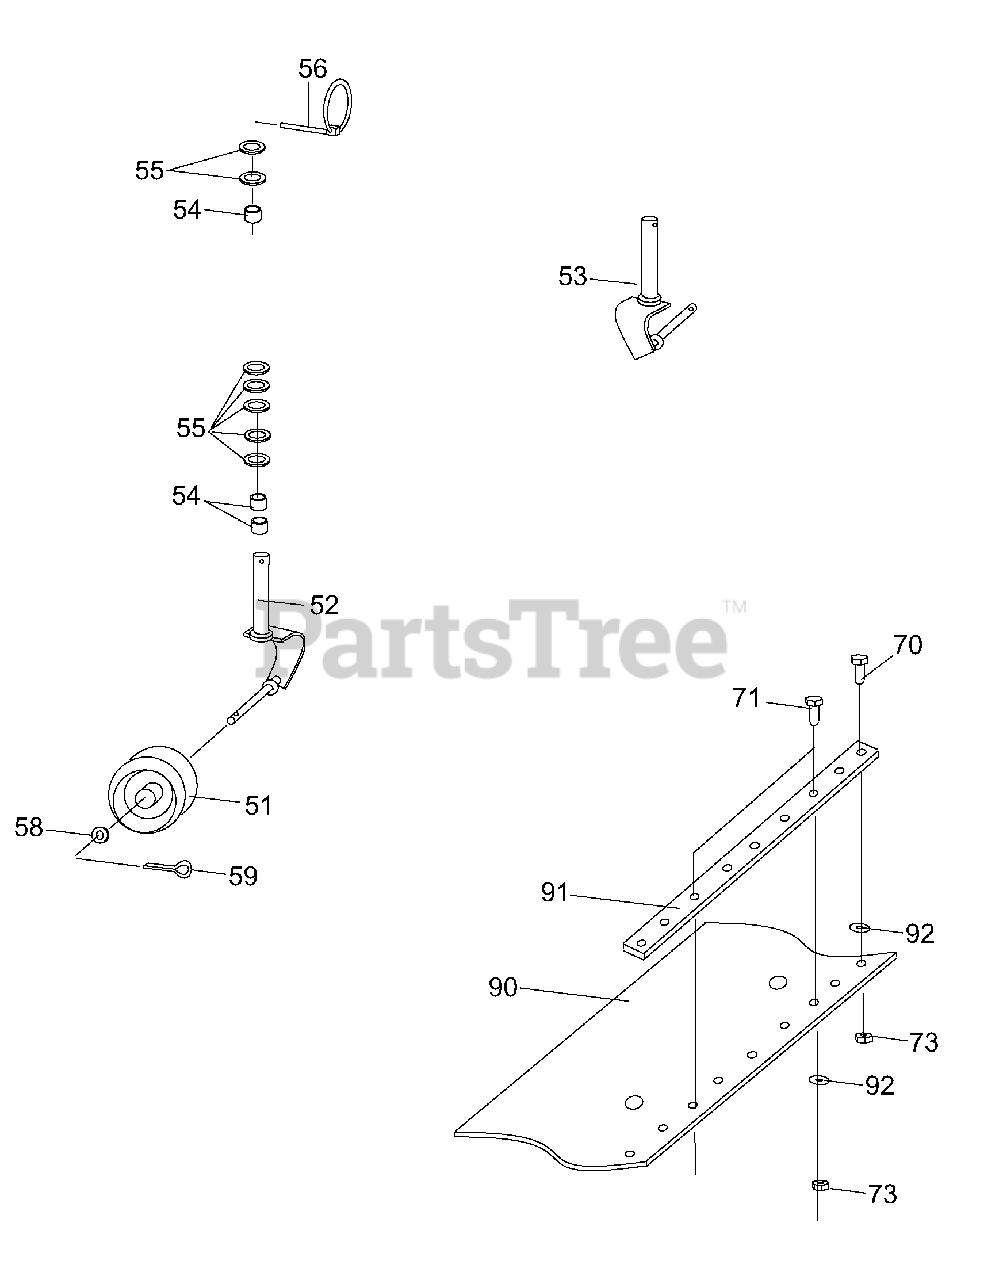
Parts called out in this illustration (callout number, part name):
14	Pulley SPA 144-1
17	V-Belt
18	Collar
19	Belt Guard
20	Support Wheel
21	Flail, Flail Mower
24	Gear Box, 1:1
25	Universal Joint
26	Drive Shaft
28	Pin, Spring
38	Guard Plate
39	Screw, Special
43	Guard, Shaft
51	Support Wheel
57	Bearing, Plastic
63	Nipple, Crease
80	Screw, Lock
91	Reinforcement strap
93	Screw, special
101	Shaft, Flail mower
